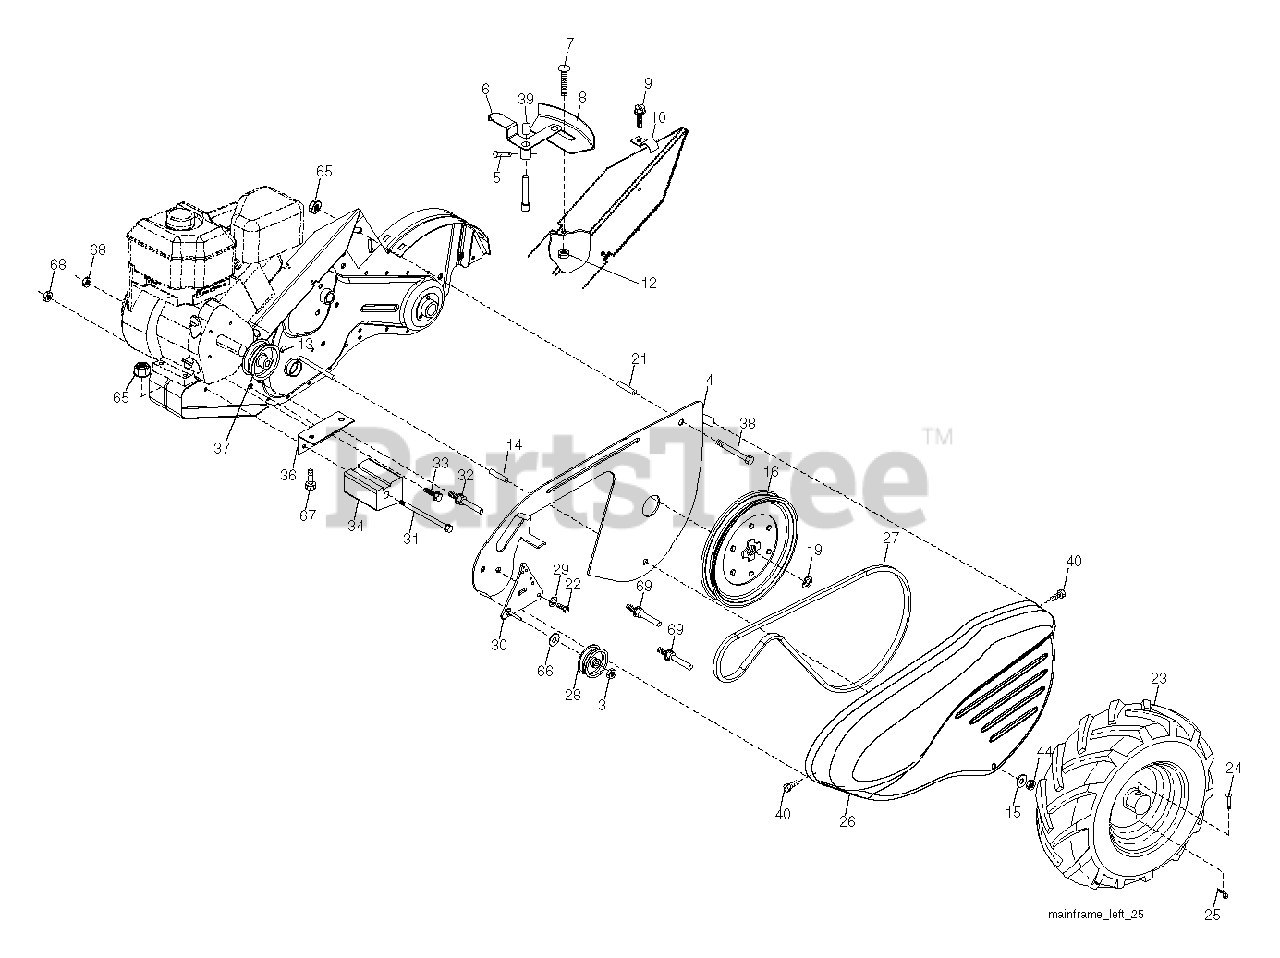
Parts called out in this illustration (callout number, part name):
3	NUT.HEX.3/8-16UNC
4	SHIELD.INNER.BELT.GUARD.RT
5	PIN.SPIROL.FLARED
6	LEVER.ASM.SHIFT.RED
8	RP.PANEL.SHIFT
9	TAPPING SCREW
10	CONDUIT.CLIP.PLATED
12	NUT
14	SPACER CRT
15	WASHER
16	SHEAVE, TRANSMISSION
19	RETAINING RING LT
21	SPACER-SPLIT.327 X .42
23	TIRE.13X5-6.CHEVRON.TILLER
24	RIVET,DRILLED
25	RETAINER M
26	GUARD.BELT.TILLER.ORANGE
27	V-BELT
28	PULLEY-IDLER TI
30	BRACKET.ASM.IDLER.BLACK
31	BOLT.FIN.HEX.3/8-16UNC
32	SHIFT ARM CRT
33	BOLT
34	COUNTERWEIGHT.LH.CRT
36	BRACKET LH CRT
37	ENGINE PULLEY
38	BOLT
39	CAP.PLUNGER.BLACK
40	SCREW.HEX.WSH.SLT.#10-24X.50
44	NUT.71038.31-18.HEX.NYLOCK
65	LOCKNUT-FLANGE 5/16-18
66	WASHER
67	BOLT, HEX 5/16-18X1-3/4
69	KEEPER.BELT.ENGINE
